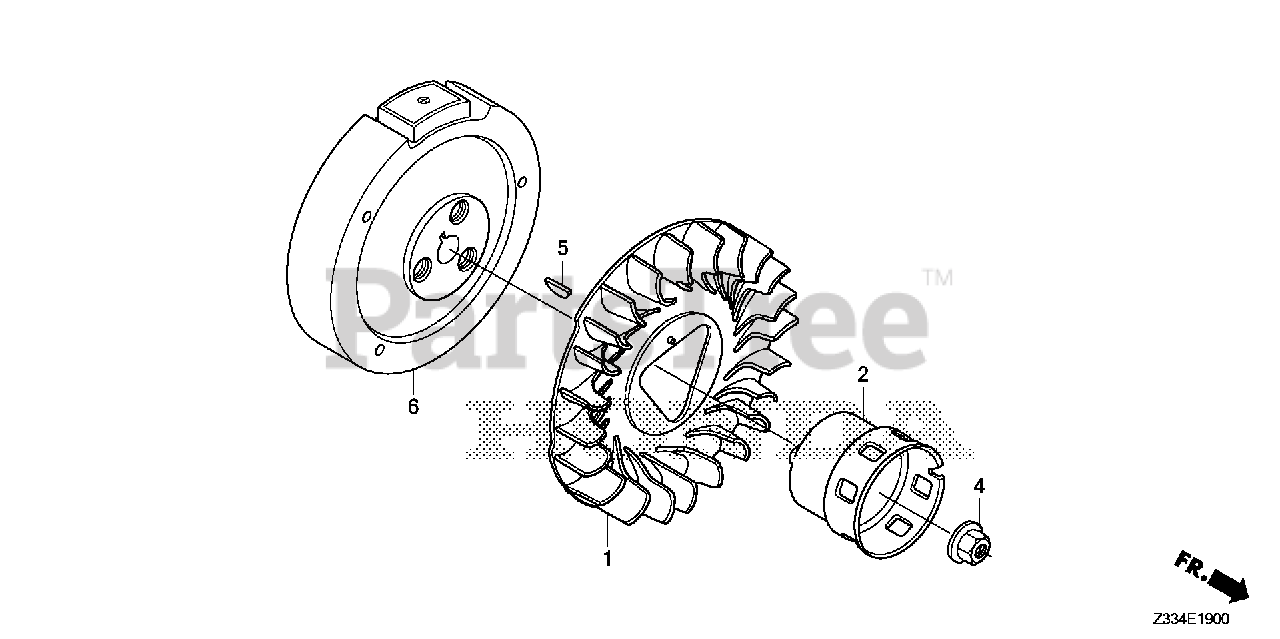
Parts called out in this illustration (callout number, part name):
1	FAN, COOLING
2	PULLEY, STARTER
4	NUT, SPECIAL (16MM)
5	KEY, SPECIAL WOODRUFF (25X18)
6	FLYWHEEL (LAMP)
